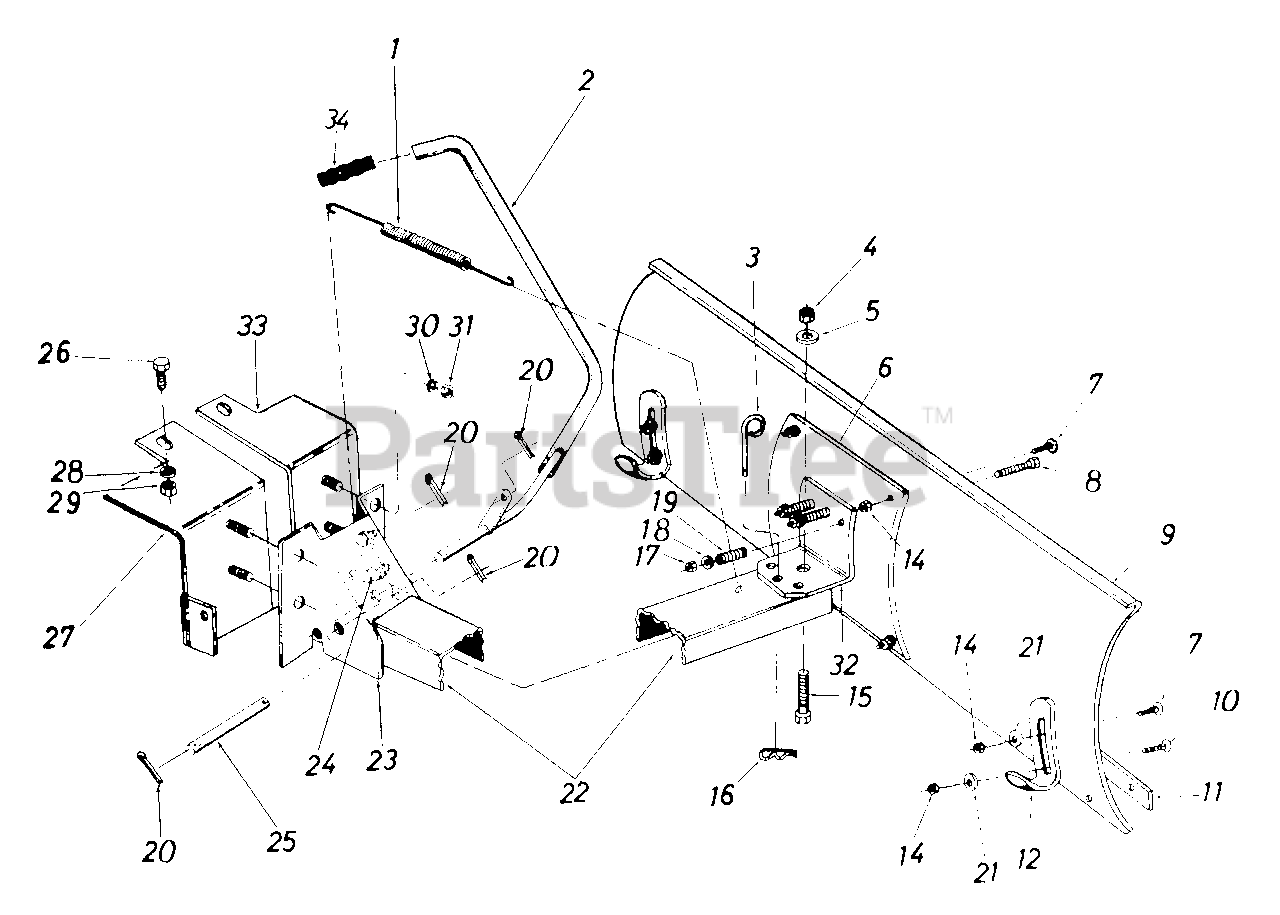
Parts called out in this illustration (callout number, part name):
1	Extension Spring
2	Lift Handle Ass'y.
3	Pivot Lock Pin
4	Hex Cent. L-Nut 1/2-13 Thd.
5	Fl-Wash. 17/32" I.D. x 1.25" Lg.
6	Reinforcement Plate
7	Carriage Bolt 5/16-18 x .75" Lg.
8	Hex Bolt 3/8-16 x 3.75" Lg. Grade 5
9	42" Blade
10	Carriage Bolt 5/16-18 x 1" Lg.
11	42" Wear Plate
12	Shoe Skid
14	Hex Cent. L-Nut 5/16-18 Thd.
15	Hex Bolt 1/2-13 x 1.25" Lg.
16	Int. Cotter Pin
17	Hex Cent. L-Nut 3/8-16 Thd.
18	Fl-Wash. 3/8" I.D.
19	Compression Spring
20	Cotter Pin 1/8" Dia. x 1" Lg.
21	Fl-Wash. 5/16" I.D.
22	Push Bar Channel
23	Pivot Support Bracket
24	Lift Link
25	Channel Pivot Shaft
26	Hex Bolt 3/8-16 x 1" Lg. Grade 5
27	Support Bracket - R.H.
28	L-Wash. 3/8" I.D.
29	Hex Nut 3/8-16 Thd.
30	L-Wash. 3/8" I.D.
31	Hex Jam Nut 3/8-16 Thd.
32	Support Bracket
33	Support Bracket - L.H.
34	Rubber Grip
